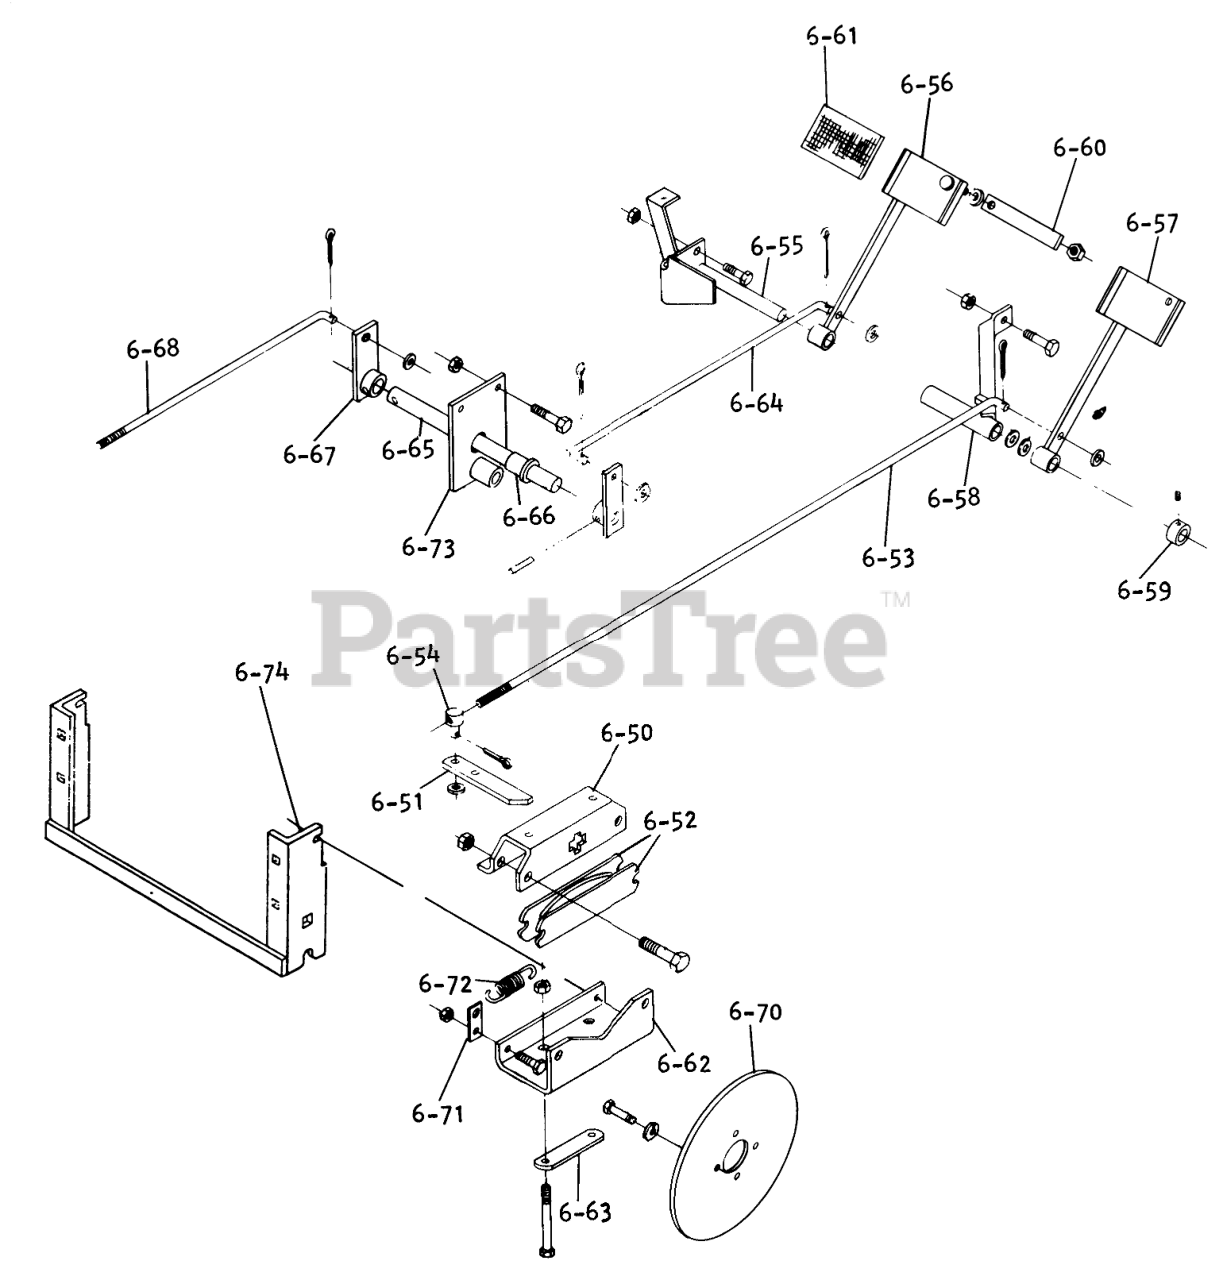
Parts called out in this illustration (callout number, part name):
6-50	Secondary Bracket
6-51	Lever Assembly
6-52	PLATE-ASSY- STATOR
6-53	Rod Assembly
6-54	Trunnion
6-55	Pedal Pivot Assembly
6-56	Pedal-L.H.
6-57	Pedal-R.H.
6-58	Brace Assembly
6-59	Collar
6-61	Brake Pedal Pad
6-62	Plate-Brake Mounting RH
6-63	BRACKET-REAR LINK MOUNTING
6-64	Rod Assembly
6-65	Shaft
6-66	BUSHING
6-67	Arm Assembly
6-68	Rod Assembly
6-71	Plate-Spring Anchor
6-72	SPRING
6-73	Support Bracket
